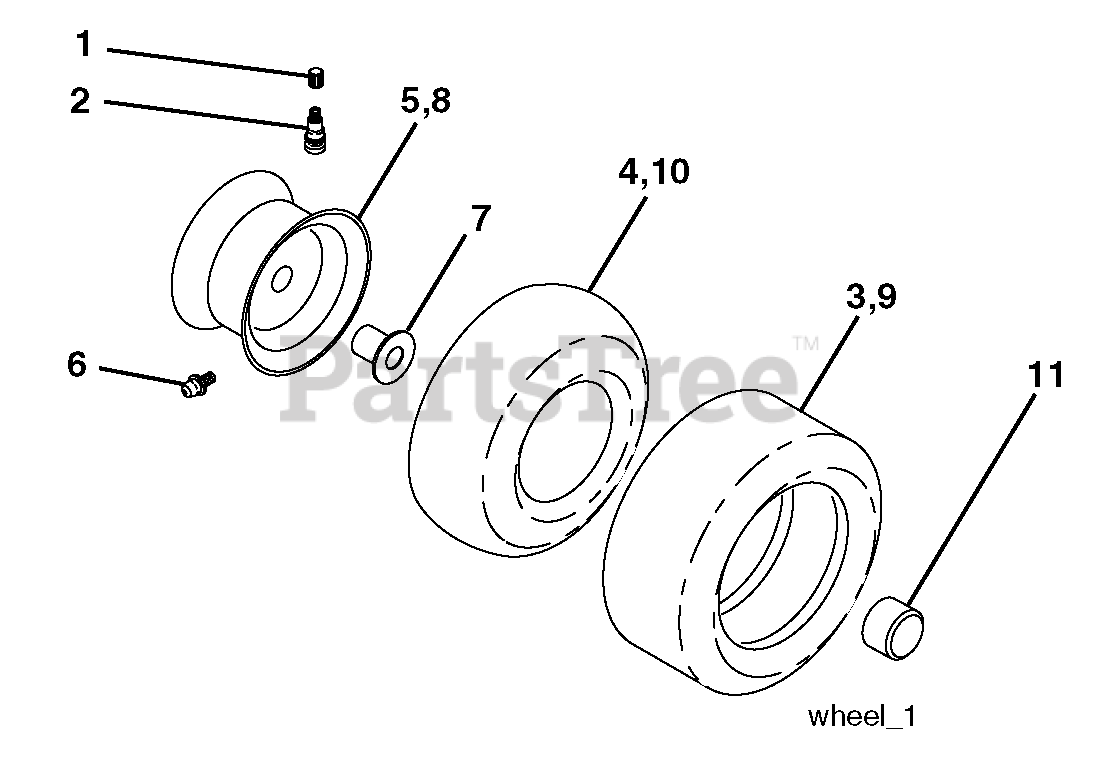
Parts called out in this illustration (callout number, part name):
1	Cap, Tire valve
2	Stem, Valve
3	Tire, Front
4	Tube, Front
5	Rim Assembly, 6" Front
6	Fitting, Grease
7	Bearing, Flange
8	Rim Assembly, 8" Rear
9	Tire, Rear 18 x 9.5-8 Turf Saver
9	Tire, Rear 18 x 9.5-8 Turf Saver LT
10	Tube, Rear
11	Cap, Hub Axle
11	Sealant, Tire (10 oz. Tube)
